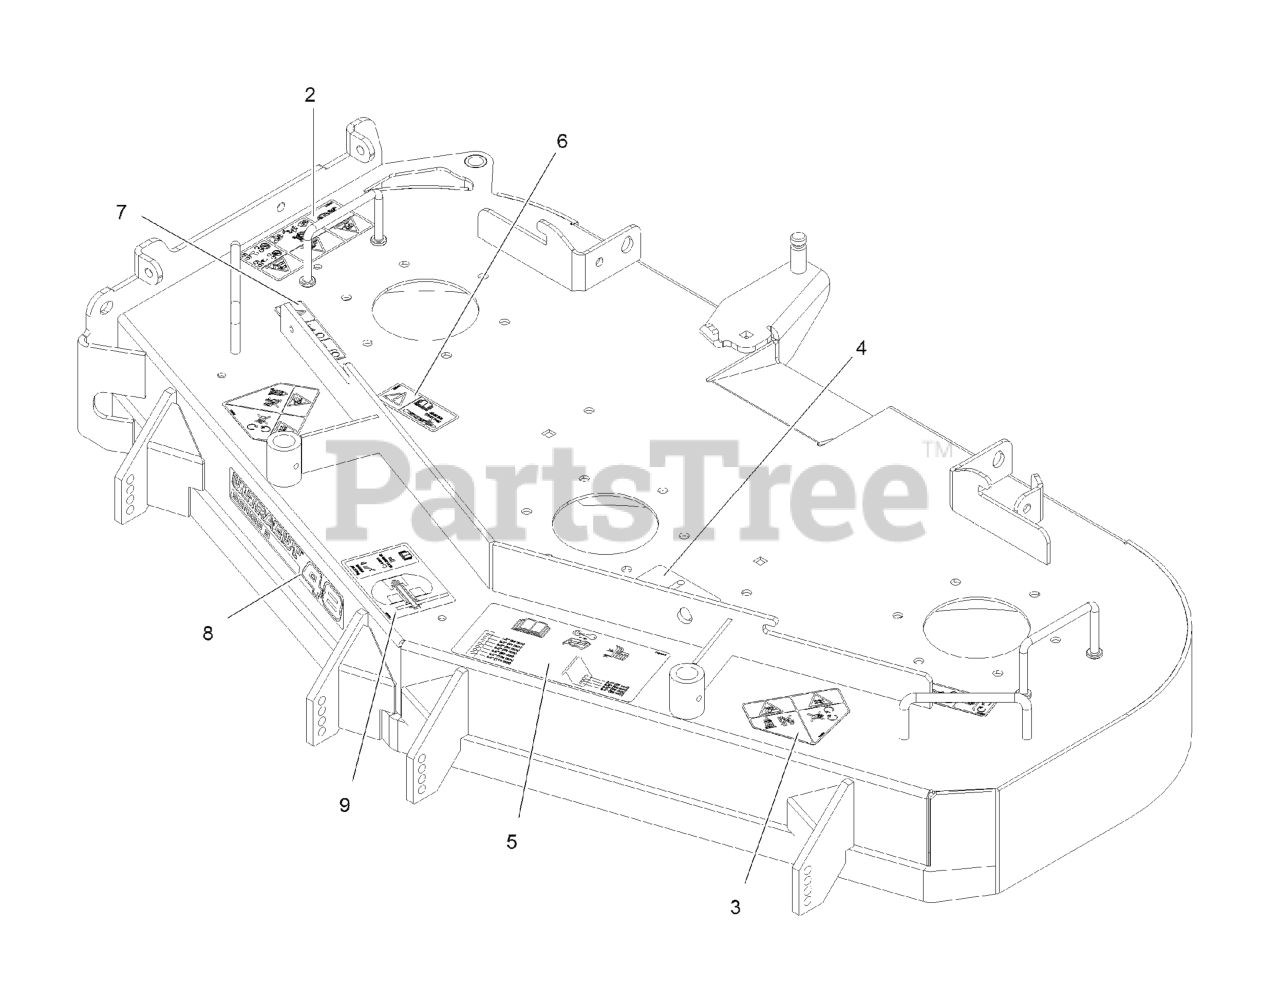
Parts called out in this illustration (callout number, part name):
2	DECAL-WARNING THROWN OBJ
3	DECAL-DANGER
4	DECAL-BELT ROUTING
5	DECAL-ANTI-SCALP
6	DECAL-BOLT TORQUE
7	DECAL-COVER, MISSING
8	DECAL-ULTRACUT 48 SERIES
9	DECAL-ROLLER MOUNTING
